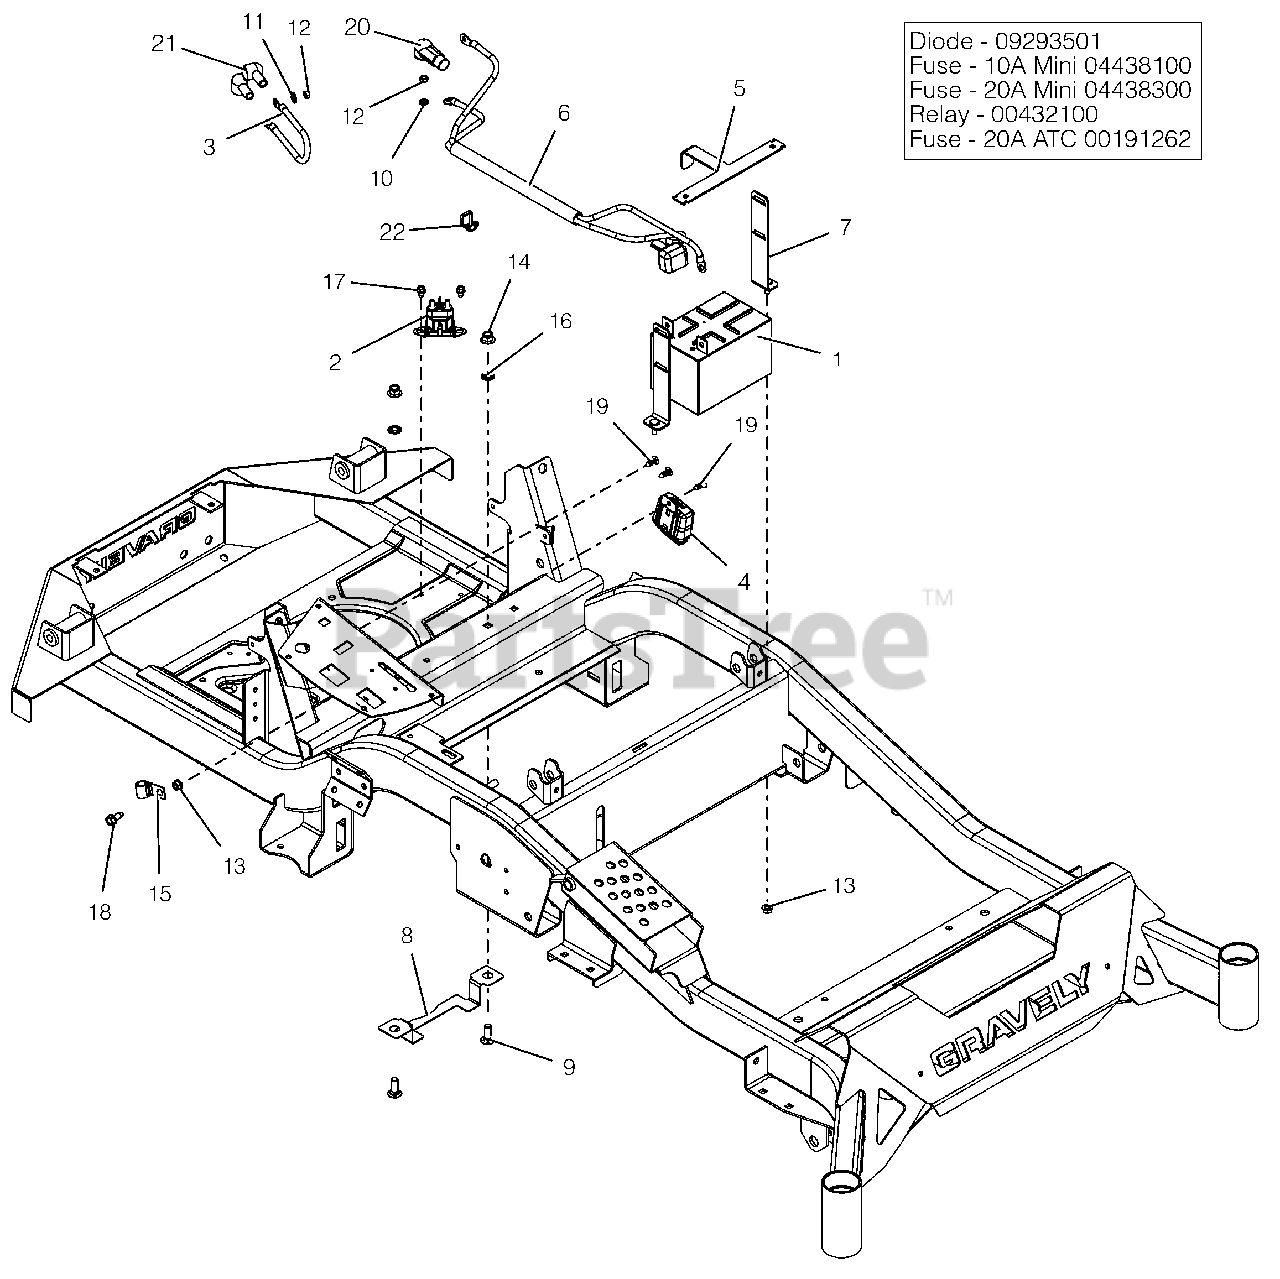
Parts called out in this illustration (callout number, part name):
1	BATTERY, 12V 12A-190CCA
2	SOLENOID, STARTER (SEALED)
3	CABLE, POS W/(2)1/4 RING 9.0LG
4	HARNESS, WIRE
4	DIODE, CONNECTOR SHELL
4	FUSE,10 AMP MINI-ATC
4	FUSE,20 AMP MINI ATC
4	RELAY,SEALED W/DIODE
4	FUSE, 20 AMP BLADE S/O
5	BRKT, BATTERY TIE DOWN
6	HARNESS, BATTERY HD
7	WMT,BATTERY MOUNT HOLD DOWN
8	GUARD, ELECTRICAL HARNESS
9	@BLT-RDHDSQNK .38-16X1.00 G5YZ
10	@WSHR-LK-EXT.262X.502X.026YWZC
11	@WSHR-LK .31X.078 REG YWZC
12	NUT-HEX M6X1.0 YWZC
13	@NUT-LK-TOP-FLG .25-20 YWZC
14	@NUT-LK-NYL-FLG .38-16 YWZC
16	NUT-PUSH .38 DIA. PAL ZINC
17	@SCR-TAP .25-20X.37 HWH YWZ TR
18	@SCR-TAP .31-18X.75 HWH TR YWZ
19	RIVET, .25 NYLON PANEL
20	BOOT, .65ID POS
21	BOOT, EYELET TERMINAL
22	CABLE TIE W/ TREE (.25 HOLE)
